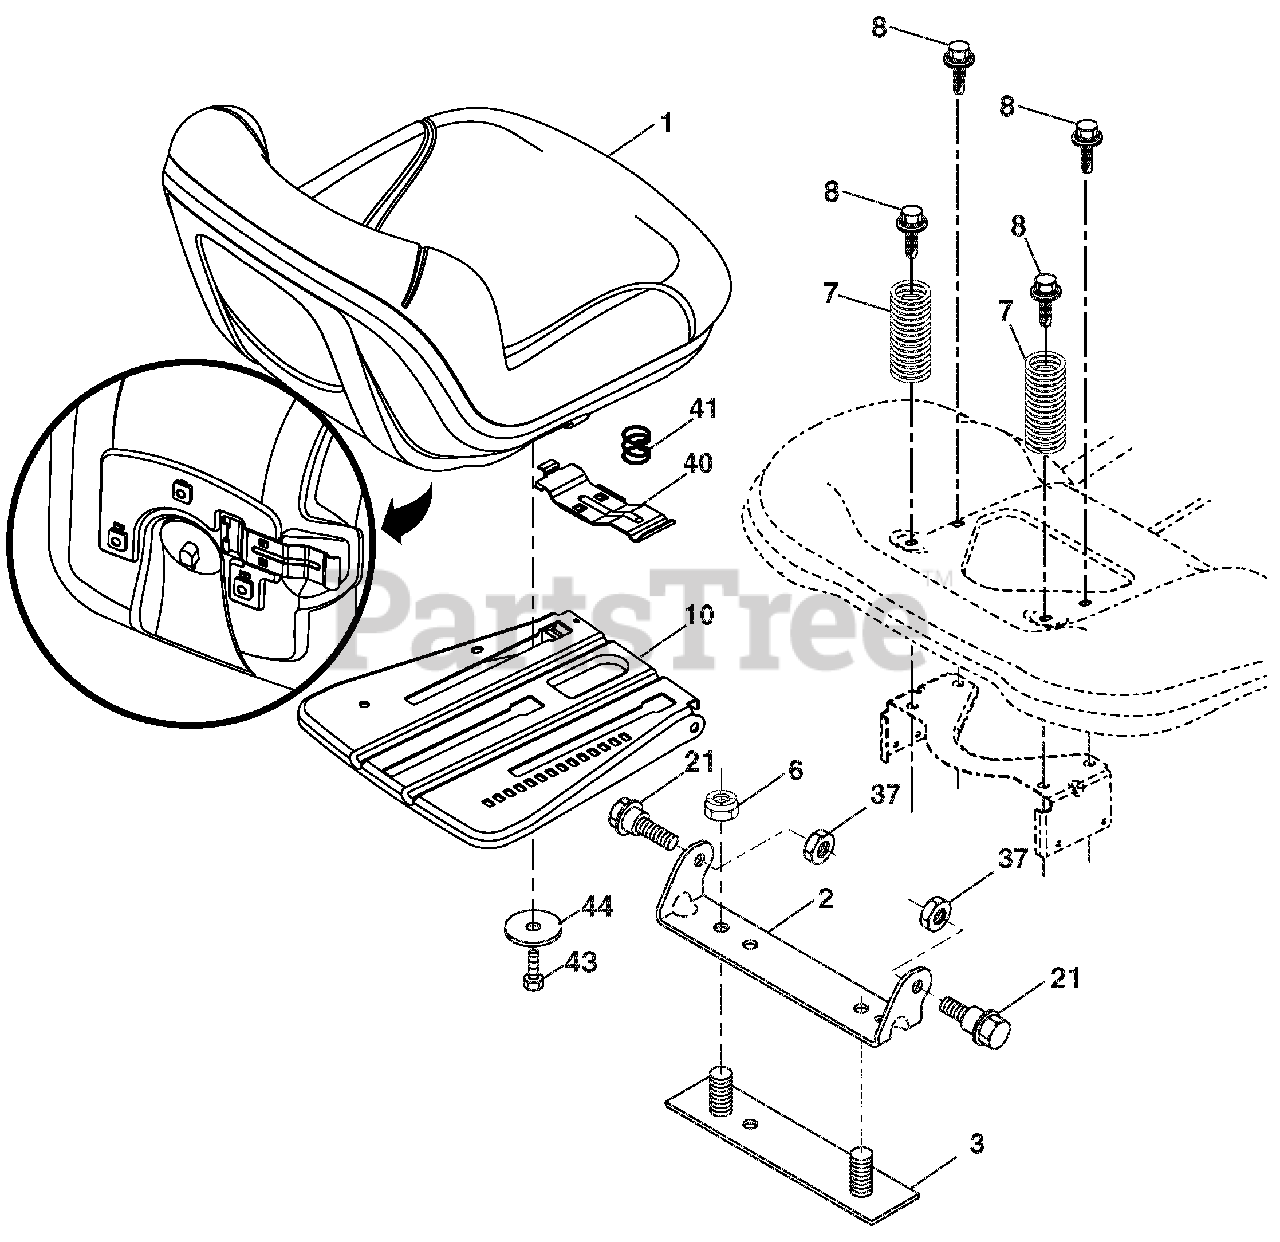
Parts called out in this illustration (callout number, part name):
1	SEAT.TA150.KB/SLD.BLK.ARIENS
2	BRACKET.PIVOT.FENDER.2002
3	STRAP ASM.FENDER.94
6	Locknut, Washer Insert 3/8-16
7	SPRING.SEAT.CPRSN.2.250.BLK.ZI
8	BOLT.5/16-18UNCX3/4 W/SEMS.BLK
10	PAN ASM.SEAT.3PT.
21	BOLT.SHLD.5/16-18 UNC-2A.BLK D
37	Locknut, Washer Insert 5/16-18
40	HANDLE.SLIDE.SEAT.TEX.MILSCO
41	SPRING.LATCH.SEAT.TEX
43	BOLT.FIN.HEX.3/8-16UNC X 3/4
44	WASHER.13/32 X 2 3/8 X 12GA.
